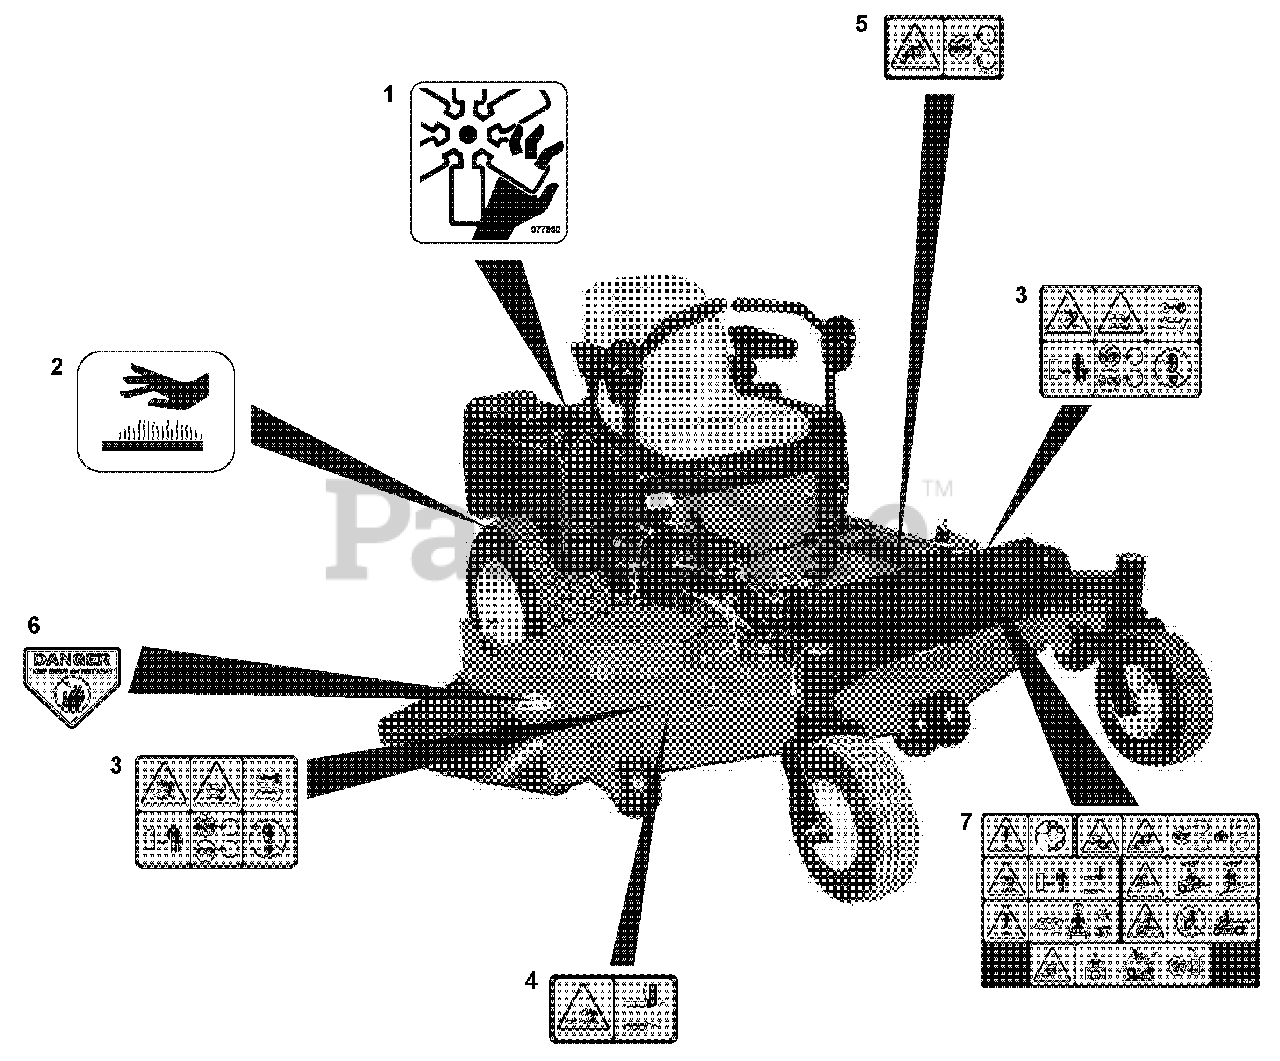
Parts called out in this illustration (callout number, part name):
1	Decal, Danger Fan
2	Decal, Hot Surface
3	Decal, Mower Safety
4	Decal, Safety Deck, Guarding
5	Decal, Safety Guarding
6	Decal, Danger
7	Decal, Safety, Main
